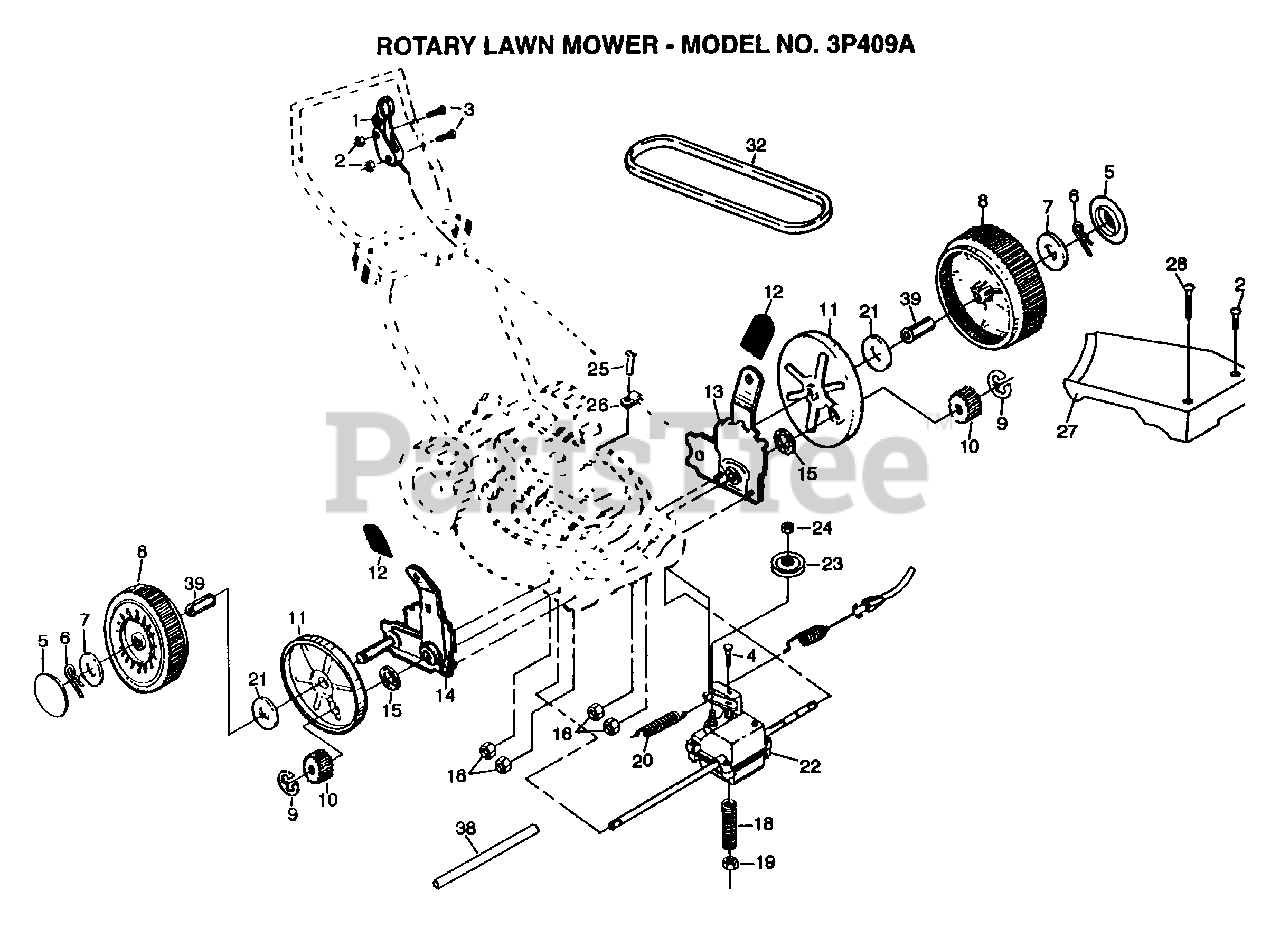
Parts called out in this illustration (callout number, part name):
1	CONTROL.DRIVE
2	LOCKNUT
3	SCREW
4	BOLT.1/4-20X2.0
5	HUB CAP
6	RETAINER CLIP PM
7	WASHER
8	WHEEL.8X2.LP.PR
9	E-RING.7/16.RE.
10	PINION.GEAR
11	DUST SHROUD PM
12	KNOB PM
15	WASHER PM
18	SPRING.TENSION
20	SPRING
21	WASHER FLUT
23	PULLEY.DRIVEN
24	LOCKNUT
25	TAPPING SCREW
26	GUIDE CLIP PM
27	COVER DRIVE BLK
38	DRV SHAFT TUBE PM
39	BUSHING.HEX
